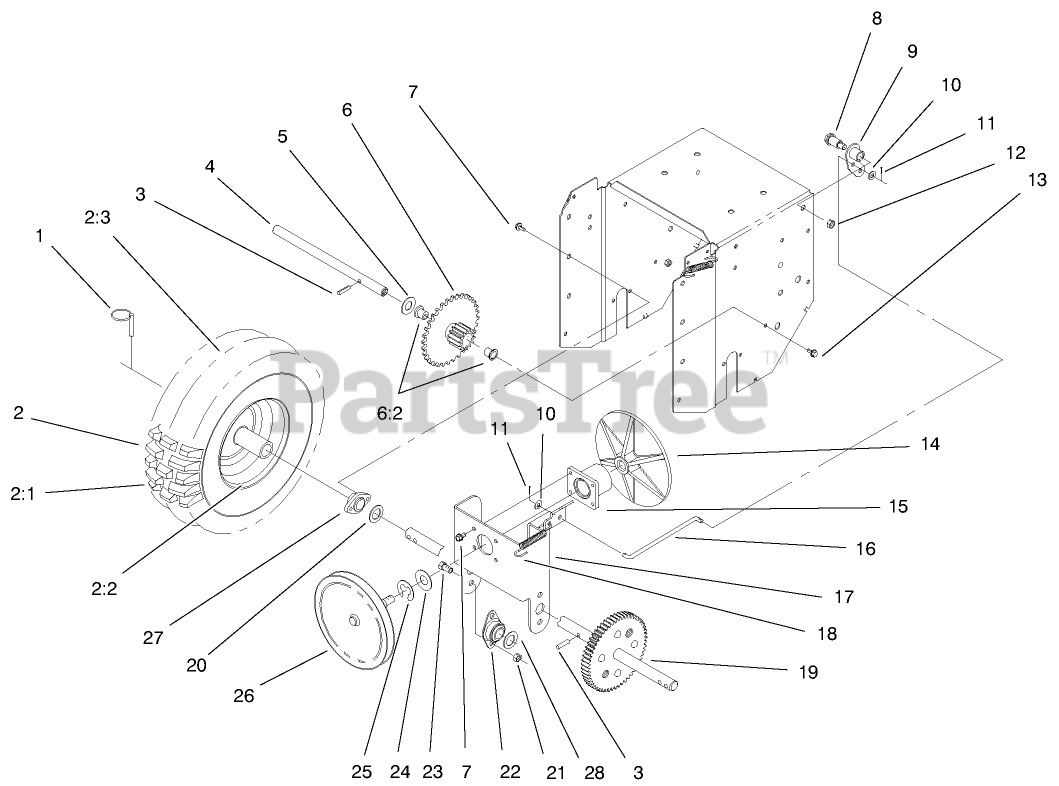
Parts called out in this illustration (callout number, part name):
1	PIN-LYNCH
2	ASM-Wheel
2:2	RIM-WHEEL
2:3	TUBE-INNER
3	PIN-ROLL, SLOTTED
4	SHAFT - INTERMEDIATE
5	WASHER
6	GEAR/BUSHING ASM
7	SCREW-HWH
8	BOLT - SHOULDER
9	HUB-PIVOT
10	WASHER
11	PIN-COTTER
13	SCREW-HWHTF
14	DISC - FRICTION
16	ROD - ENGAGE
17	FRAME-FRICTION PLATE
20	WASHER-THRUST
21	NUT-LOCK, NI
22	BUSHING
23	SCREW-HH
24	WASHER-THRUST
25	RING-RETAINING, EXT
26	PULLEY/SHAFT ASM
27	BEARING-AXLE
28	WASHER-THRUST
